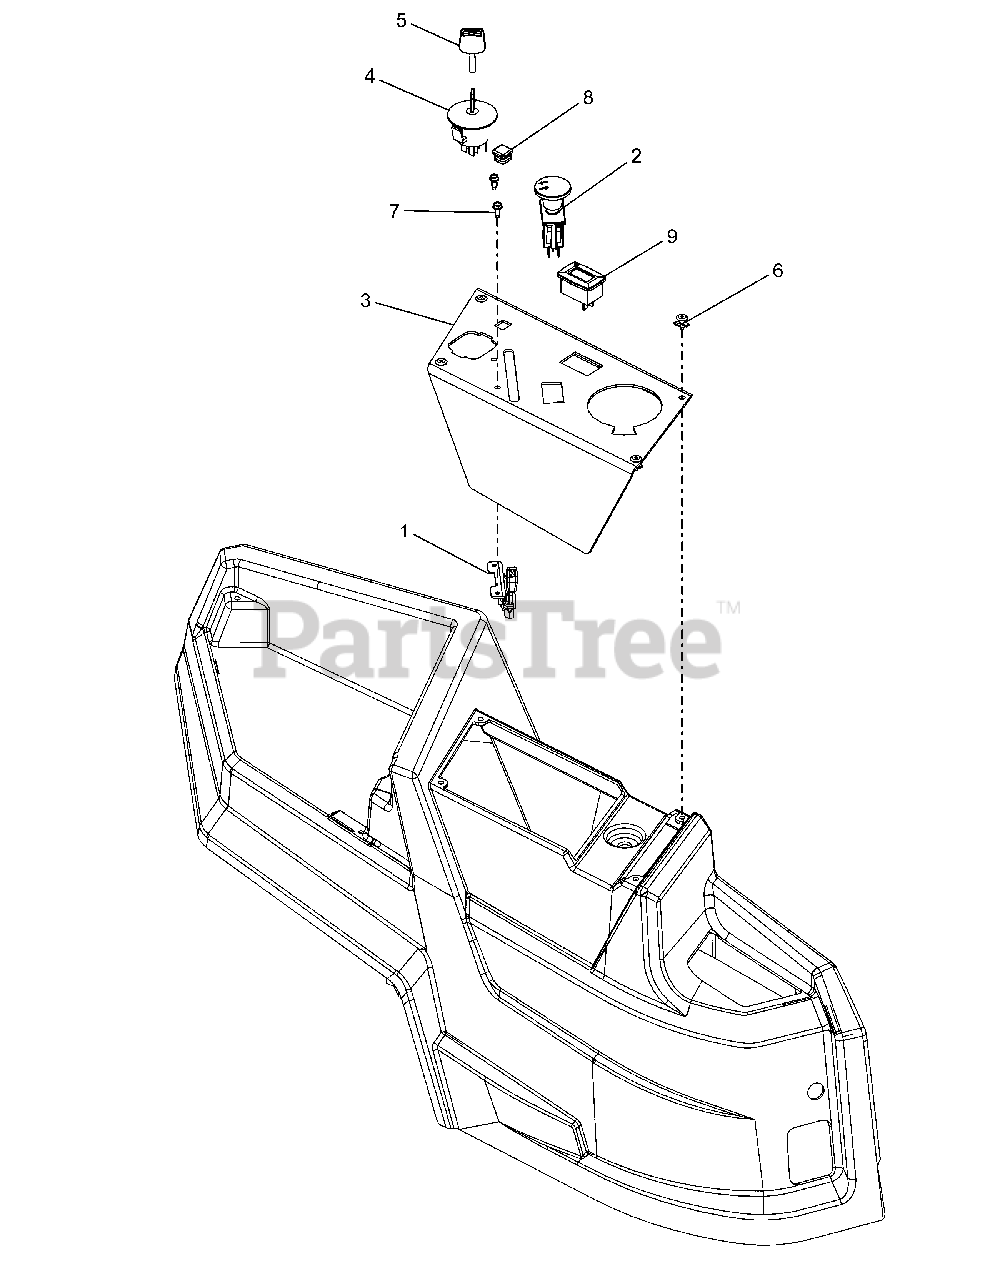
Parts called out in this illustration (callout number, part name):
1	CABLE - THROTTLE CONTROL
2	SWITCH, CLUTCH (YELLOW)
3	PANEL, CONTROL
4	KEYSWITCH-IGNITION 4 POS
5	KEY, IGNITION
6	RIVET, PLASTIC .195 DIA.
7	@SCR-TAP 10-24X.50 HWH TR YWZC
8	PLUG, 5/8" SQ BLACK (14-20GA)
9	METER, HOUR W/MAINTENANCE
